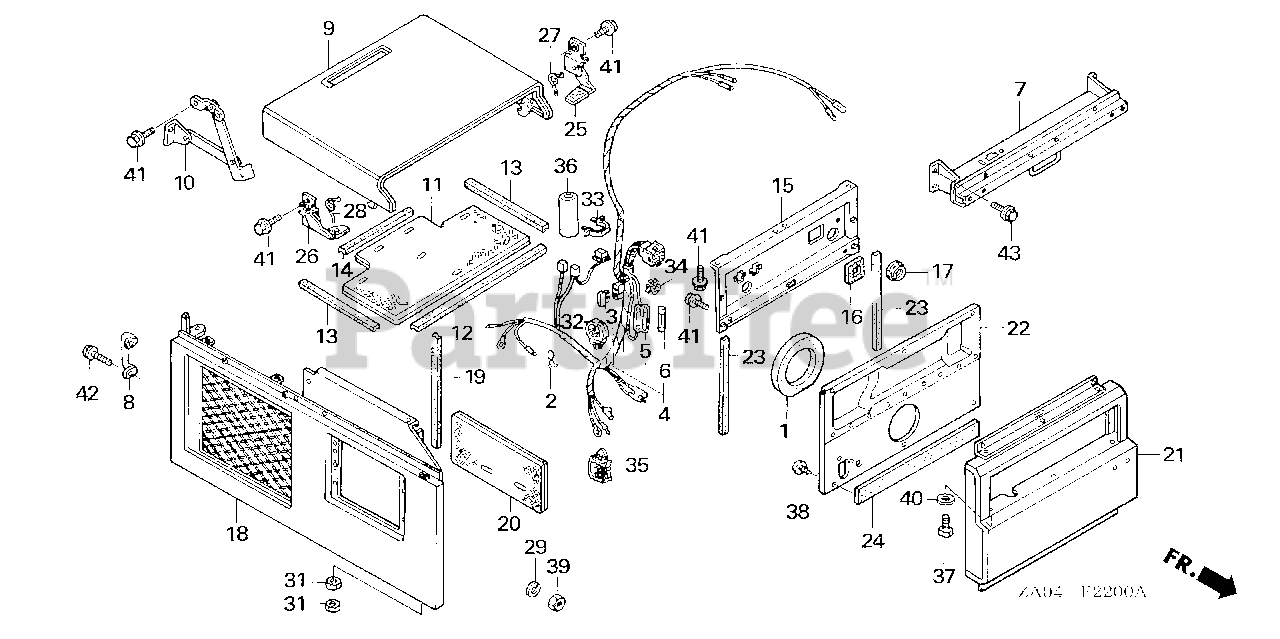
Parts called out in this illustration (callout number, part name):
1	SEAL, TIMING BELT COVER
3	RECTIFIER ASSY., SILICON (STANLEY)
3	RECTIFIER ASSY., SILICON (SHINDENGEN)
4	WIRE HARNESS ASSY.
5	CASE, FUSE CONNECTOR (SUMITOMO)
6	FUSE (10A)
6	FUSE B (10A)
7	HANDLE, FR. *NH105* (MAT BLACK)
8	HOOK, RR. (UPPER)
9	COVER, TOP *NH35M* (CLOUD SILVER METALLIC)
10	STOPPER, TOP COVER
11	INSULATOR, TOP COVER
12	RUBBER A, TOP COVER SEAL
13	RUBBER B, TOP COVER SEAL
14	RUBBER C, TOP COVER SEAL
15	SEPARATOR, FR.
16	SEAL, FR. SEPARATOR
17	GROMMET, PETCOCK SHAFT
18	COVER, R. SIDE *B9* (ATLANTIS BLUE)
19	RUBBER, SIDE COVER SEAL
20	INSULATOR, R. SIDE COVER
21	PANEL, FR. *B9* (ATLANTIS BLUE)
22	COVER, FR. PANEL
23	RUBBER A, FR. PANEL SEAL
24	RUBBER B, FR. PANEL SEAL
25	LOCK, R. TOP COVER
26	LOCK, L. TOP COVER
27	SPRING, R. COVER LOCK
28	SPRING, L. COVER LOCK
29	WASHER, SPRING (6MM)
31	NUT, HEX. (8MM)
32	CLIP, WIRE HARNESS
33	CLIP, WIRE HARNESS
34	CLIP, ENGINE STOP SWITCH CORD
35	CLIP, WIRE HARNESS (25MM)
36	TUBE, CORD (22MM)
37	BOLT, HEX. (5X12)
38	SCREW, TAPPING (4X6)
39	NUT, HEX. (6MM)
40	WASHER, PLAIN (5MM)
41	BOLT, FLANGE (6X10)
42	BOLT, FLANGE (6X28)
43	BOLT, FLANGE (8X16) Use from Engine SN 1000016.
